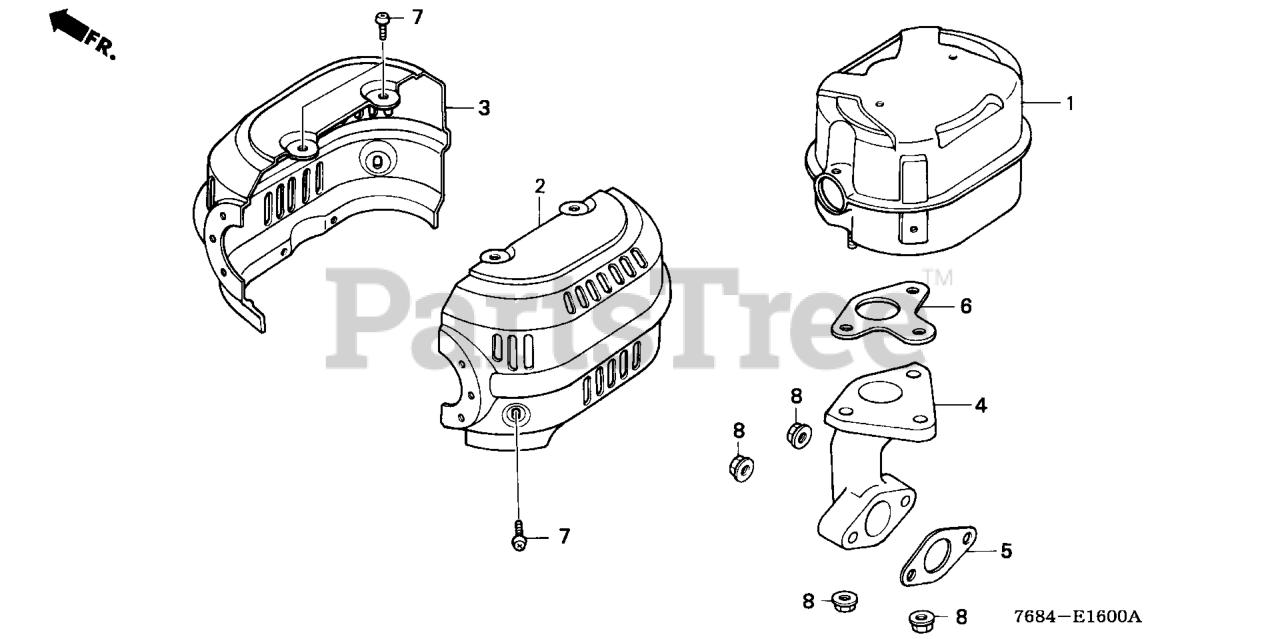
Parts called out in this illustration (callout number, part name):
1	MUFFLER
2	PROTECTOR, R. MUFFLER (STD)
3	PROTECTOR, L. MUFFLER (STD)
4	PIPE, EX.
5	GASKET, EX. PIPE Use up to Engine SN 2949254.
5	GASKET, EX. PIPE (WACKER)
6	GASKET, MUFFLER
6	GASKET, MUFFLER (NIPPON LEAKLESS)
7	SCREW, TAPPING (5X8)
8	NUT, FLANGE (8MM)
